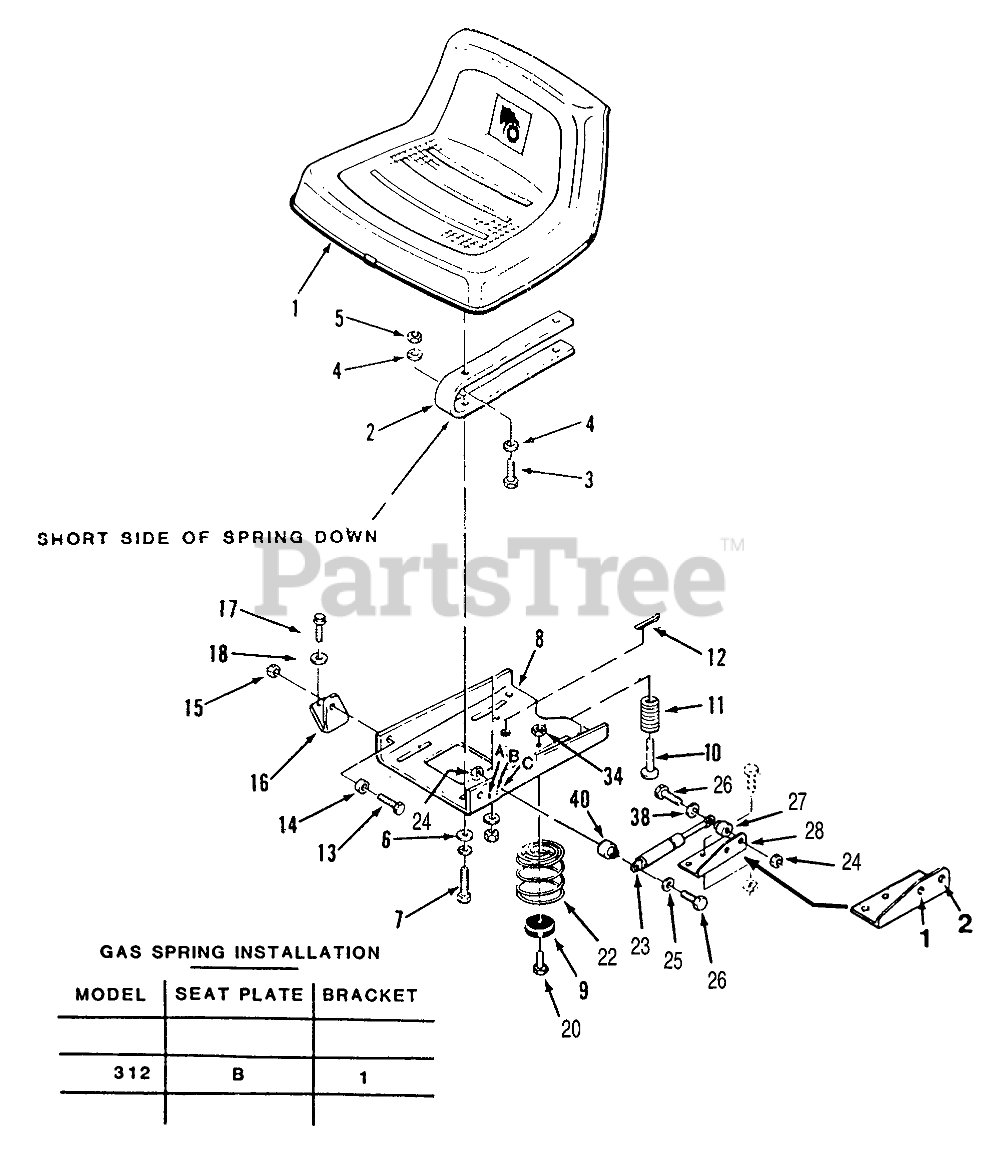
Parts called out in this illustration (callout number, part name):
2	Seat Spring
3	Bolt
4	Lockwasher
5	Nut
6	WASHER 5/16 SAE
7	HHCS
8	PLATE-SEAT PIVOT B
9	BUMPER
11	SPRING-SEAT SWITCH
12	Cotter Pin
13	HHCS
14	BUSHING
15	Nut
16	Bracket-Pivot RH
17	Bolt
18	WASHER 5/16 SAE
19	RIVET
20	Bolt
21	Nut
22	SPRING
23	GAS SPRING
24	Nut
26	Bolt
27	SPACER
28	BRACKET-CYLINDER R
